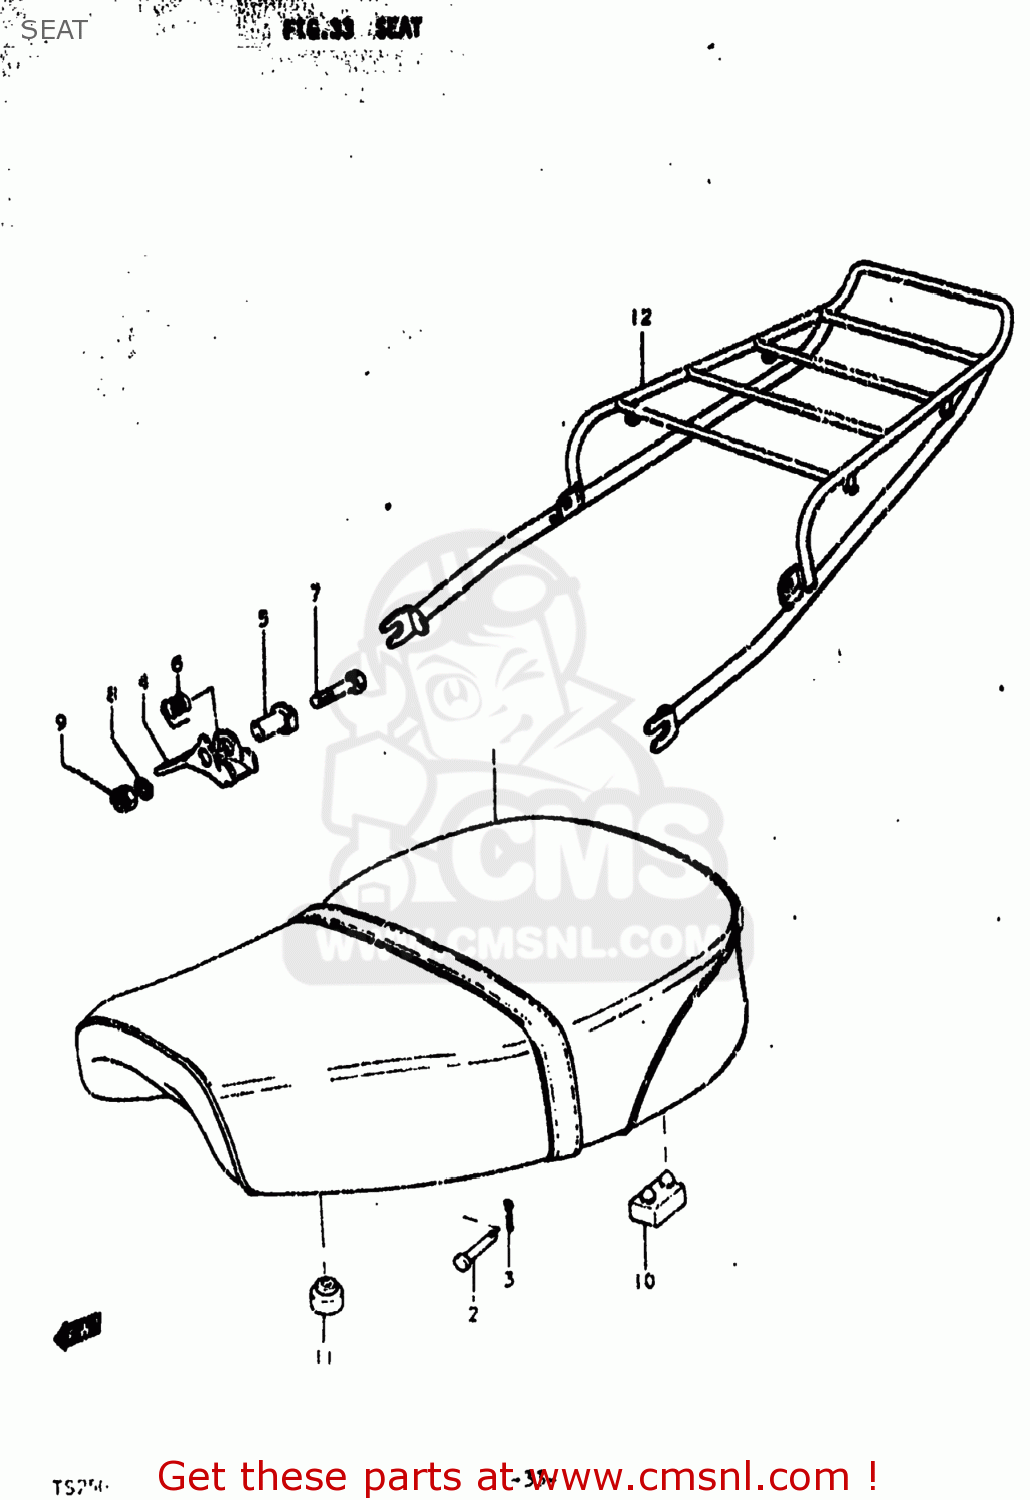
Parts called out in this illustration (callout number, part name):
1	SEAT ASSEMBLY
2	PIN
3	PIN
4	STRIKER,SEAT LOCK
5	STRIKER,SEAT LOCK
6	SPRING
7	BOLT 8X45
8	LOCK WASHER
9	NUT
10	CUSHION
11	CUSHION(11.5X22X20)
12	CARRIER
